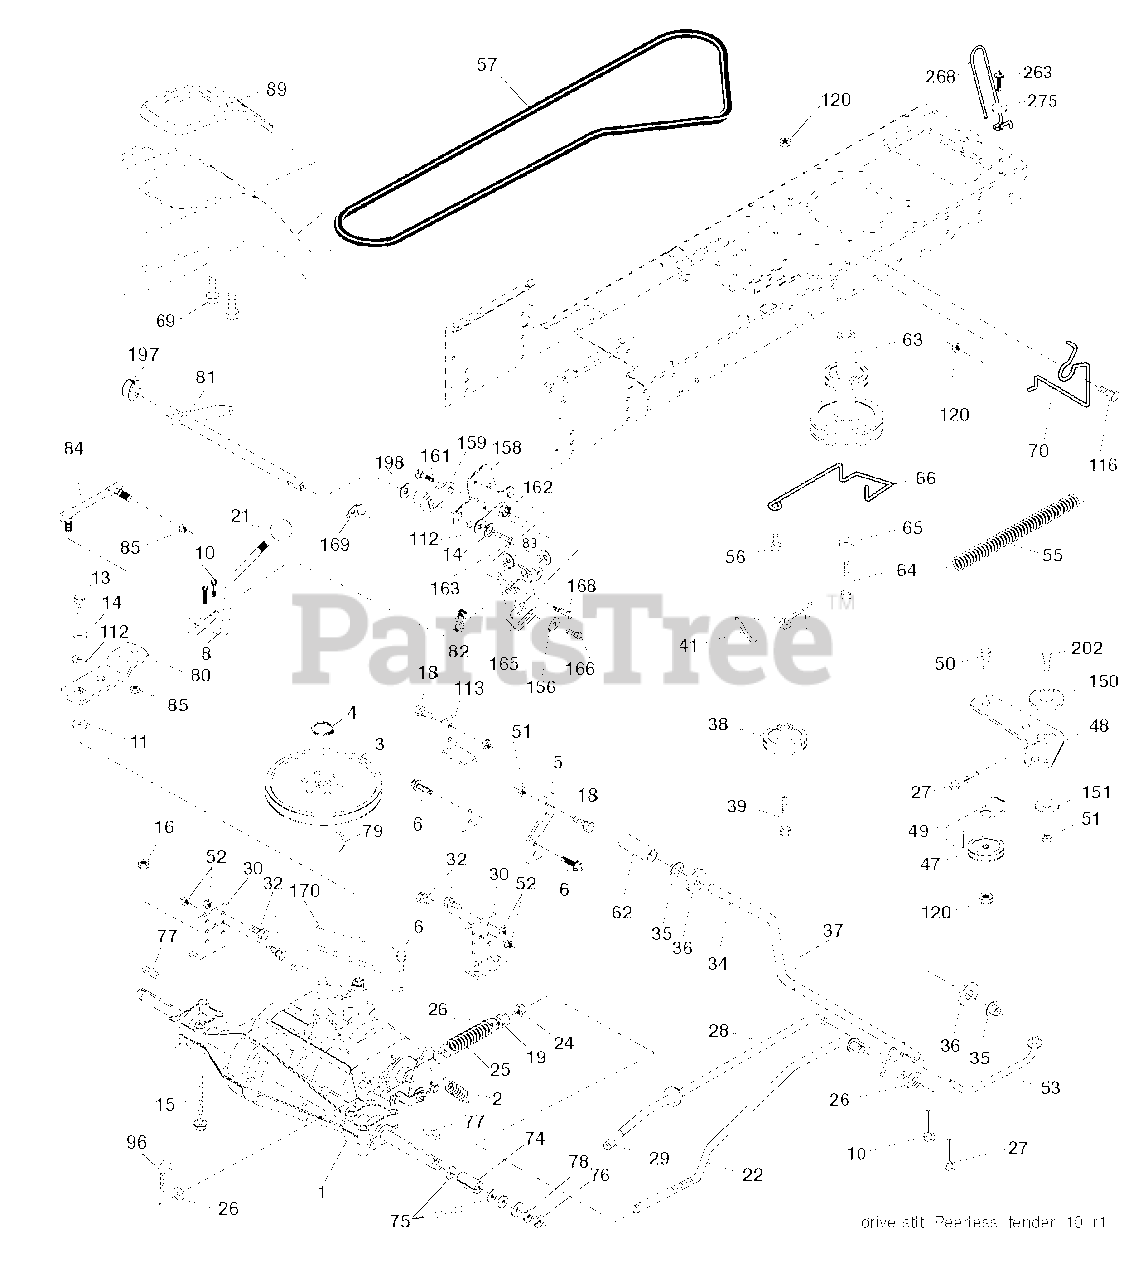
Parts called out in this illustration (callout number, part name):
2	SPRING,BRAKE RETURN
3	PULLEY TRANS
4	RETAINING RING LT
5	STRAP TORQUE
6	SCREW 5/16"
8	ROD SHIFT FENDER ADJUST LT
10	PIN COTTER
11	WASH-SHFT PLT LT
13	BOLT 1/4-28X3/4
14	LOCKWASHER
15	BOLT HEX 5/16-18 GR 5
16	NUT.71038.31-18.HEX.NYLOCK
19	NUT
21	KNOB T (1/2-HOLE)
22	ROD BRAKE
24	NUT
25	SPRING ROD LT
27	COTTER PIN
28	ROD, PARKING BRAKE
29	PLUNGER CAP
30	BRKT, MOUNT TRNSAXLE
32	BOLT
34	SHAFT, FOOT PEDAL
35	BEARING.NYLON
36	WASHER LT
37	DRIVE PIN
38	PULLEY IDLER COMPOSITE
41	KEEPER, BELT IDLER
47	IDLER PULLEY
48	BELLCRANK, CLUTCH
49	RETAIN BELT
50	BOLT.3/8-16X1.50
51	LOCKNUT
52	LOCKNUT
53	LINK.CLUTCH.7.66.2005
55	SPRING, RETURN LT
56	SCREW.3/8-16
57	BELT, V GROUND DRIVE 95 25
62	PEDAL COVER T
63	ENGINE PULLEY
64	BOLT HEX 7/16-20X4-1/4"
65	LOCKWASHER
66	KEEPER BELT ENGINE
69	SCREW.HI-LO.CONSOLE
70	KEEPER BELT ENG
74	SPACER AXLE
76	E-RING LT
77	SQUARE KEY
80	ARM SHIFT
82	SHIFT SPRING
83	WASHER
85	NUT LOCK CENTER 1/4 -28 FNTHD
89	CONSOLE SHIFT STLT
96	RETAINER M
112	WASHER LT
113	STRAP TORQUE LH LT
116	BOLT D
120	NUT LOCK FLG 3/8-16 UNC
150	SPACER, RETAINER
151	WASHER 12/32X2X10GA
156	WASHER.SRRTD.5/16
158	BRACKET
159	HUB.SHIFT
161	BOLT
162	NUT.CROWNLOCK.1/4
165	RP BRACKET
168	BOLT.SHOULDER.5/16-18X
169	PLATE.FASTENING.CROSS.SHAFT
170	KEEPER BELT T/A
197	NYLINER SNAP 5/8" ID
198	WASHER.NYL.7/8IDX.105"HYD CR
202	BOLT
263	SCREW, 3/8-16X3/4
275	WASHER
